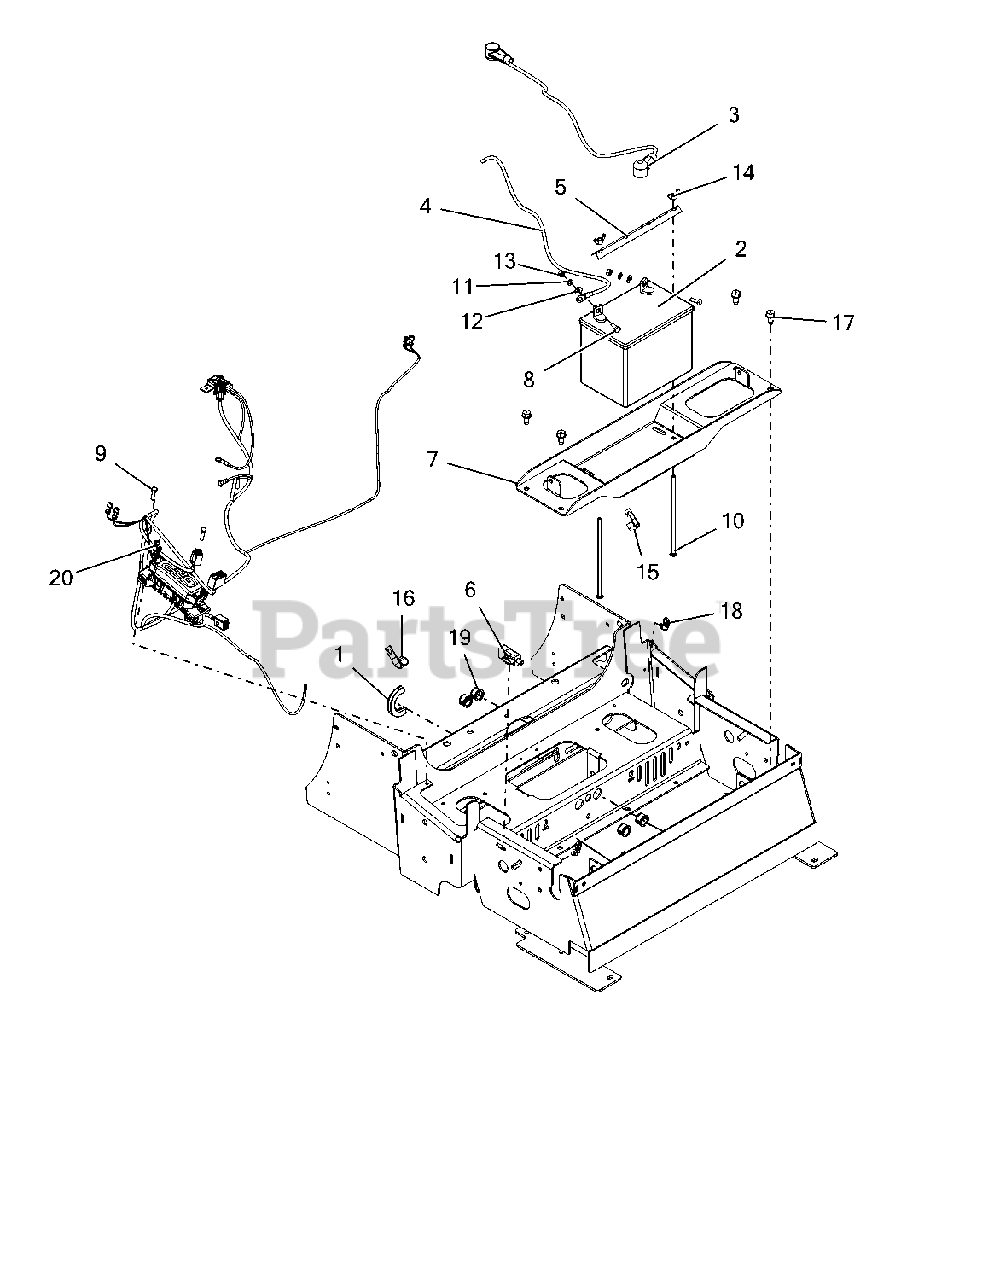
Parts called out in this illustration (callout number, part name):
1	STRIP, COWL - 1.50 LG
2	BATTERY, 300 CCA 10U1L
3	CABLE, POS BATT W/ BOOTS 6 X 35
4	CABLE, NEGATIVE BATTERY
5	HOLD DOWN - BLK
6	SWITCH, SNAP IN -N.O./N.O
7	TRAY, BATTERY-RED
8	BLT-HEX .25-20X.75 GR5 YWZC
9	@BLT-HEX M6-1.0X25 YWZC
10	BLT-RDHDSQNK .25-20X7.50 G2 YWZC
11	WSHR-LK .25X.062 REG YWZC
12	WSHR-FL-STL.281X.62X.065 YWZC
13	NUT-HEX .25-20 YWZC
14	NUT-LOCKING WING 1/4-20
15	CLAMP, J
17	SCR-TAP .38-16X.75 HWH TR YWZ
18	CABLE TIE W/ TREE (.25 HOLE)
19	BUSH, PANEL SNAP .687X.875X.56
20	HARNESS, PT200/400 WIRING
